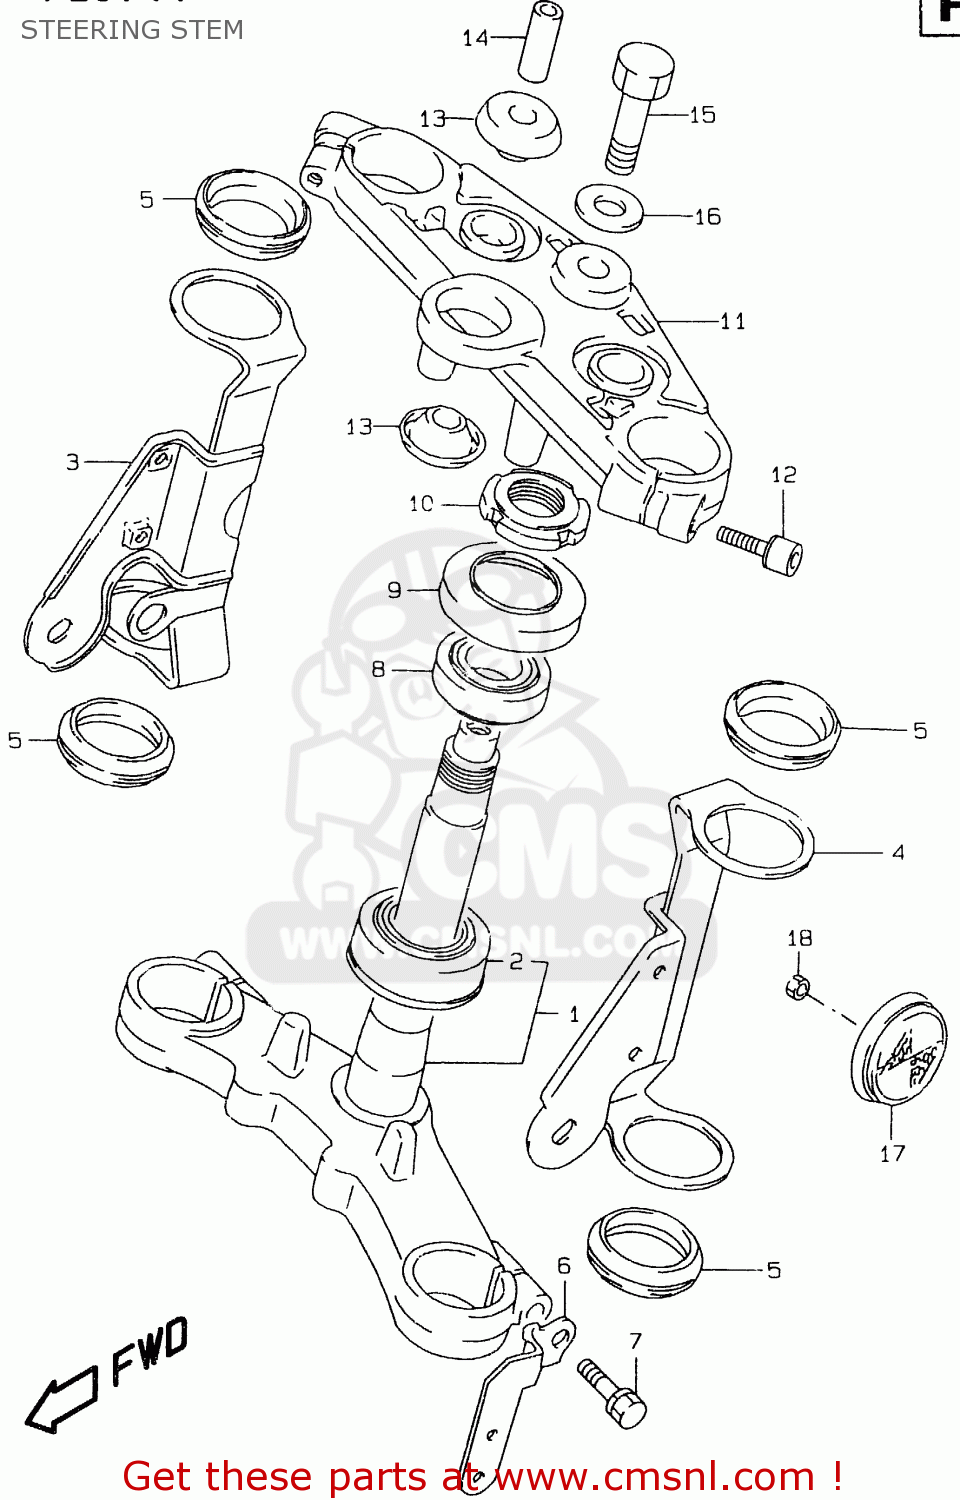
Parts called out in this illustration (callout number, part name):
1	STEM,STEERING
2	BEARING(30X55X17)
3	BRACKET,HEADLAMP,R
4	BRACKET,HEADLAMP,L
5	CUSHION,HEADLAMP BRACKET
6	BRACKET,FR SIDE RR,R
7	BOLT,STEERING STEM
8	BEARING(25X47X15)
9	SEAL,STEERING UPR DUST
10	NUT,STEERING STEM(25X44X10)
11	HEAD,STEERING STEM
12	BOLT
13	CUSHION,UPR BRACKET
14	SPACER,STEERING STEM HEAD
15	BOLT
16	WASHER,STEM HEAD(10.5X30X3.2)
17	REFLECTOR,REFLEX FR
18	NUT
